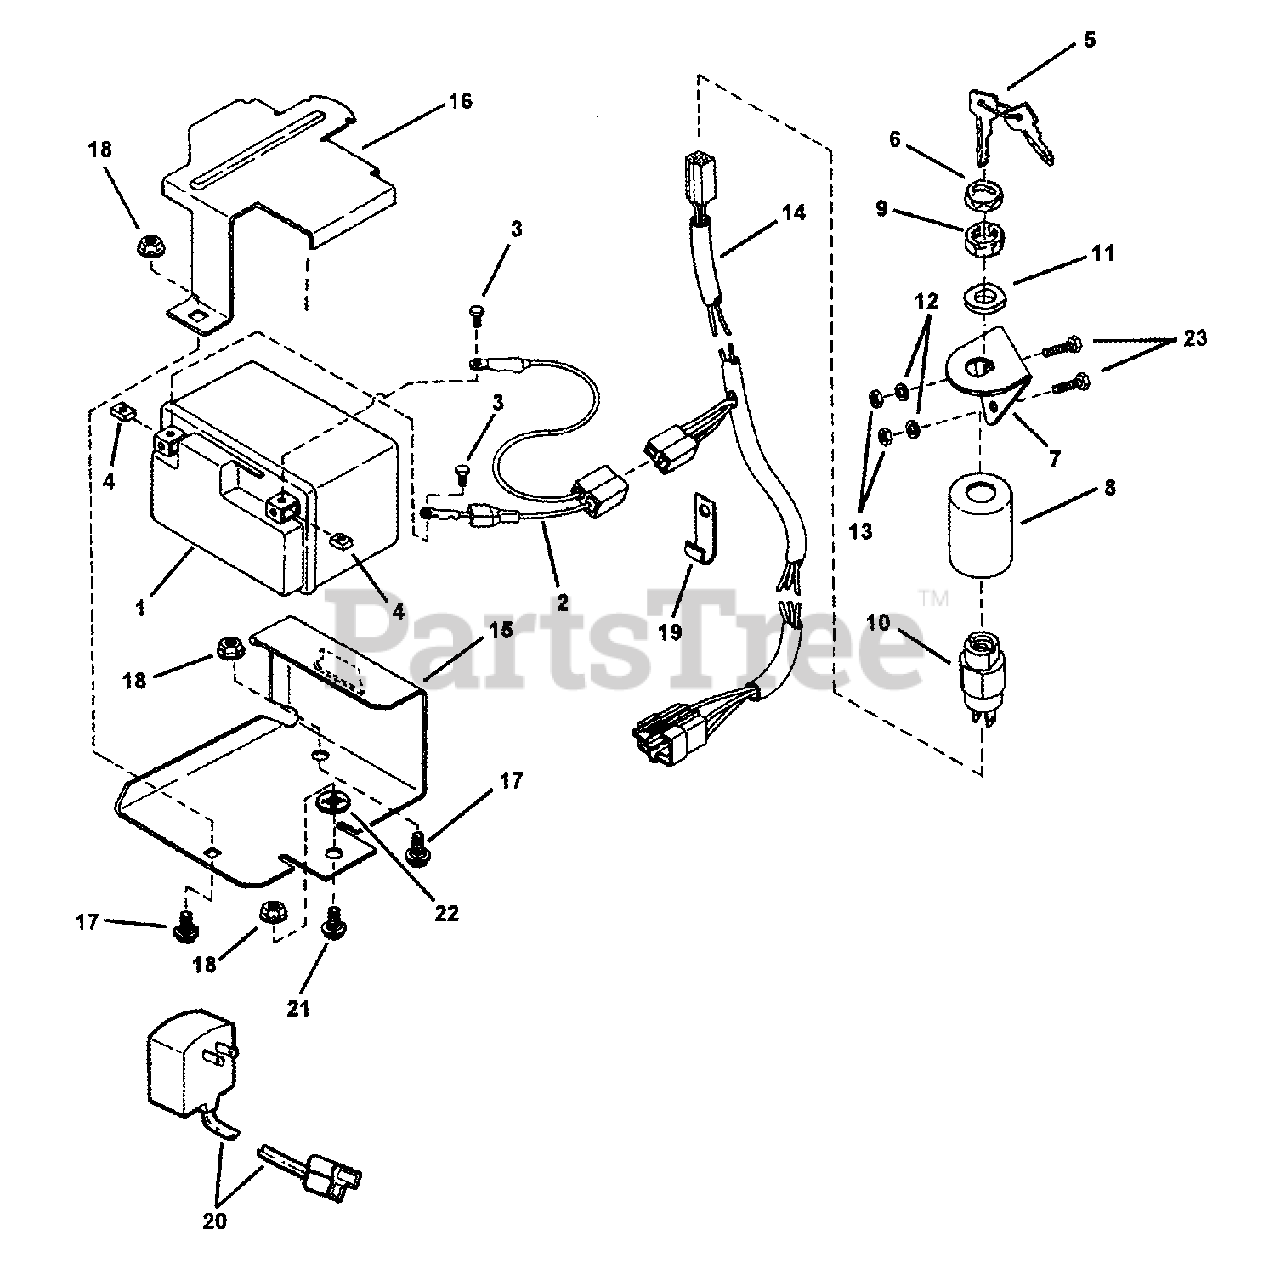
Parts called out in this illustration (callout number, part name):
1	BATTERY KIT, 12 Volt, 35 CCA (Includes items 1-4)
2	HARNESS, Battery
3	SCREW, #10-24 x 1/2" Pan Head Machine
4	NUT, #10-24 Square
5	KEY (Set of Two)
6	BEZEL (Seal & Face Nut)
7	BRACKET, Ignition Switch
8	COVER, Switch
9	NUT, 5/8-32 Hex Lock
10	SWITCH, Ignition (spring loaded ON/OFF 2 prong)
11	SPACER
12	WASHER, 1/4" Internal Tooth Lock
13	NUT, 1/4-28 Hex, GR5 or B
14	HARNESS, Wiring
15	BRACKET, Battery
16	COVER, Battery
17	BOLT, 5/16-18 x 1/2" Short Neck Carriage GR5
18	NUT, 5/16-18 Hex Flange Lock, GR5
19	CLIP, Wiring
20	CHARGER, Battery (120 Volt; 60 Hertz)
20	CHARGER, Battery (230 Volt; 50 Hertz)
21	BOLT, 5/16-18 x 5/8" Short Neck Carriage GR5
22	RETAINER, 5/16" Bolt
23	SCREW, 1/4-28 x 1-3/8" Hex Head Cap GR5
